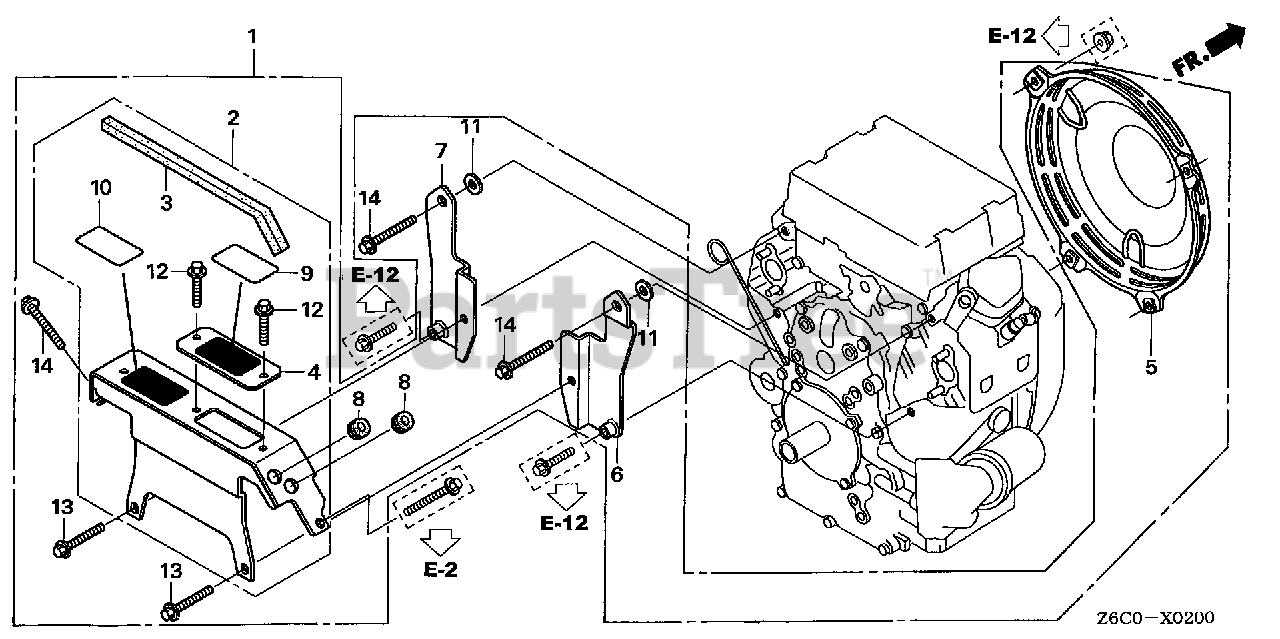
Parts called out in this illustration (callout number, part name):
1	KIT, WINTER
2	COVER ASSY., CONTROL
3	SEAL, CONTROL COVER
4	COVER B, CONTROL
5	PROTECTOR, FAN COVER
6	BRACKET, R. SHROUD
7	BRACKET, L. SHROUD
8	RUBBER, SEAT LOCK BAR CUSHION
9	LABEL, OPERATOR NOTICE (E)
10	LABEL, OPERATOR NOTICE (F)
11	WASHER, PLAIN (8MM)
12	BOLT, FLANGE (6X12) Use up to Engine SN 1543277.
13	BOLT, FLANGE (6X16) Use from Engine SN 2056820.
14	BOLT, FLANGE (8X20) Use up to Engine SN 1609606.
